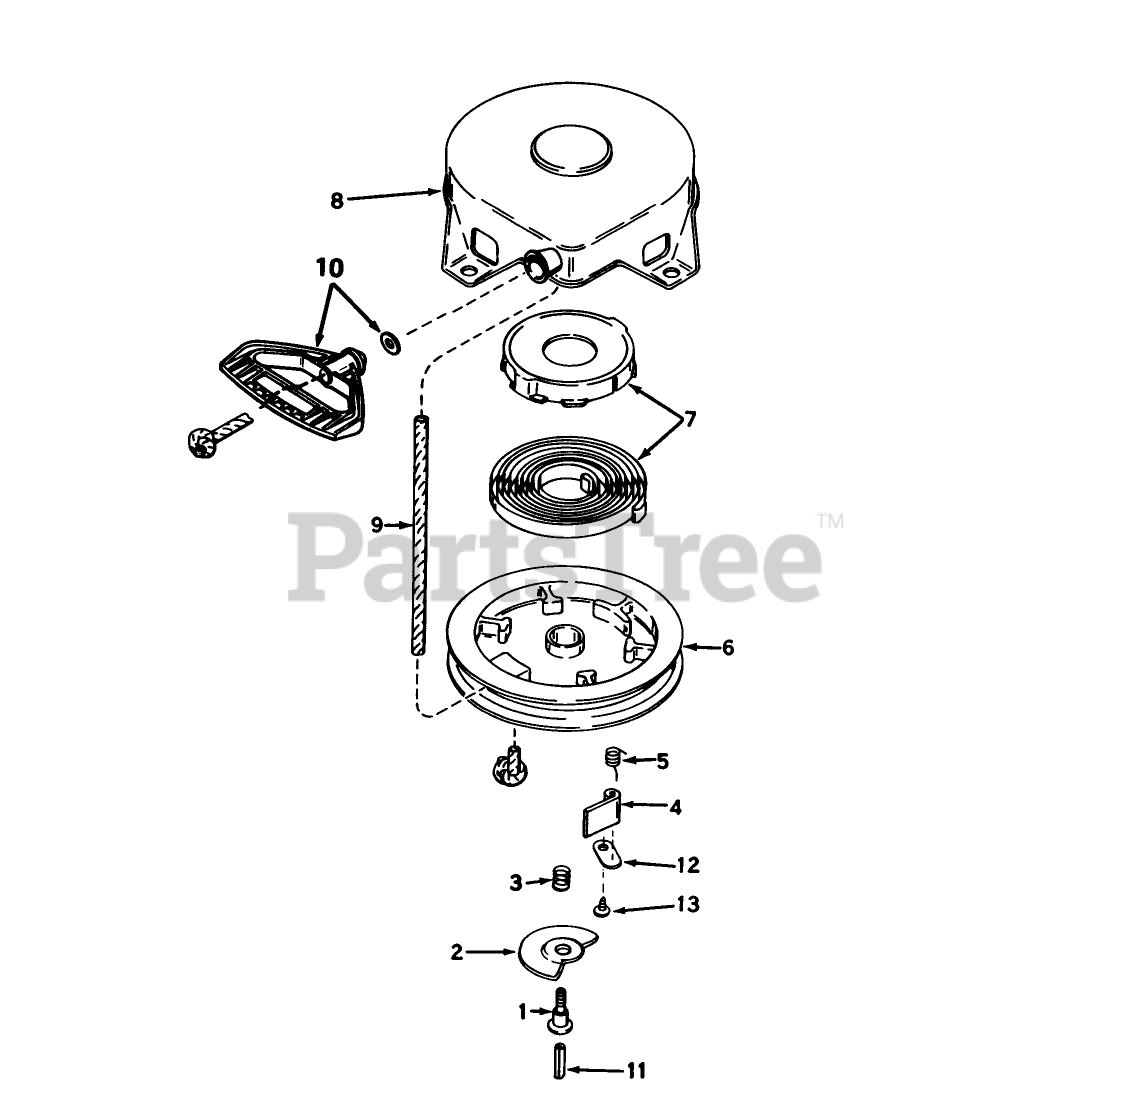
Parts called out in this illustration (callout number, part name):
1	Screw
2	Cam-Dog
3	Spring-Brake
4	Dog-Starter
5	Spring-Dog
6	Pulley
7	Spring Keeper Assy.
8	Housing Assy.-Starter (Incl. Ref. #1)
9	Rope, Starter
10	Handle-Starter, Mitten Grip
11	Centering
12	Retainer-Dog
13	Screw
